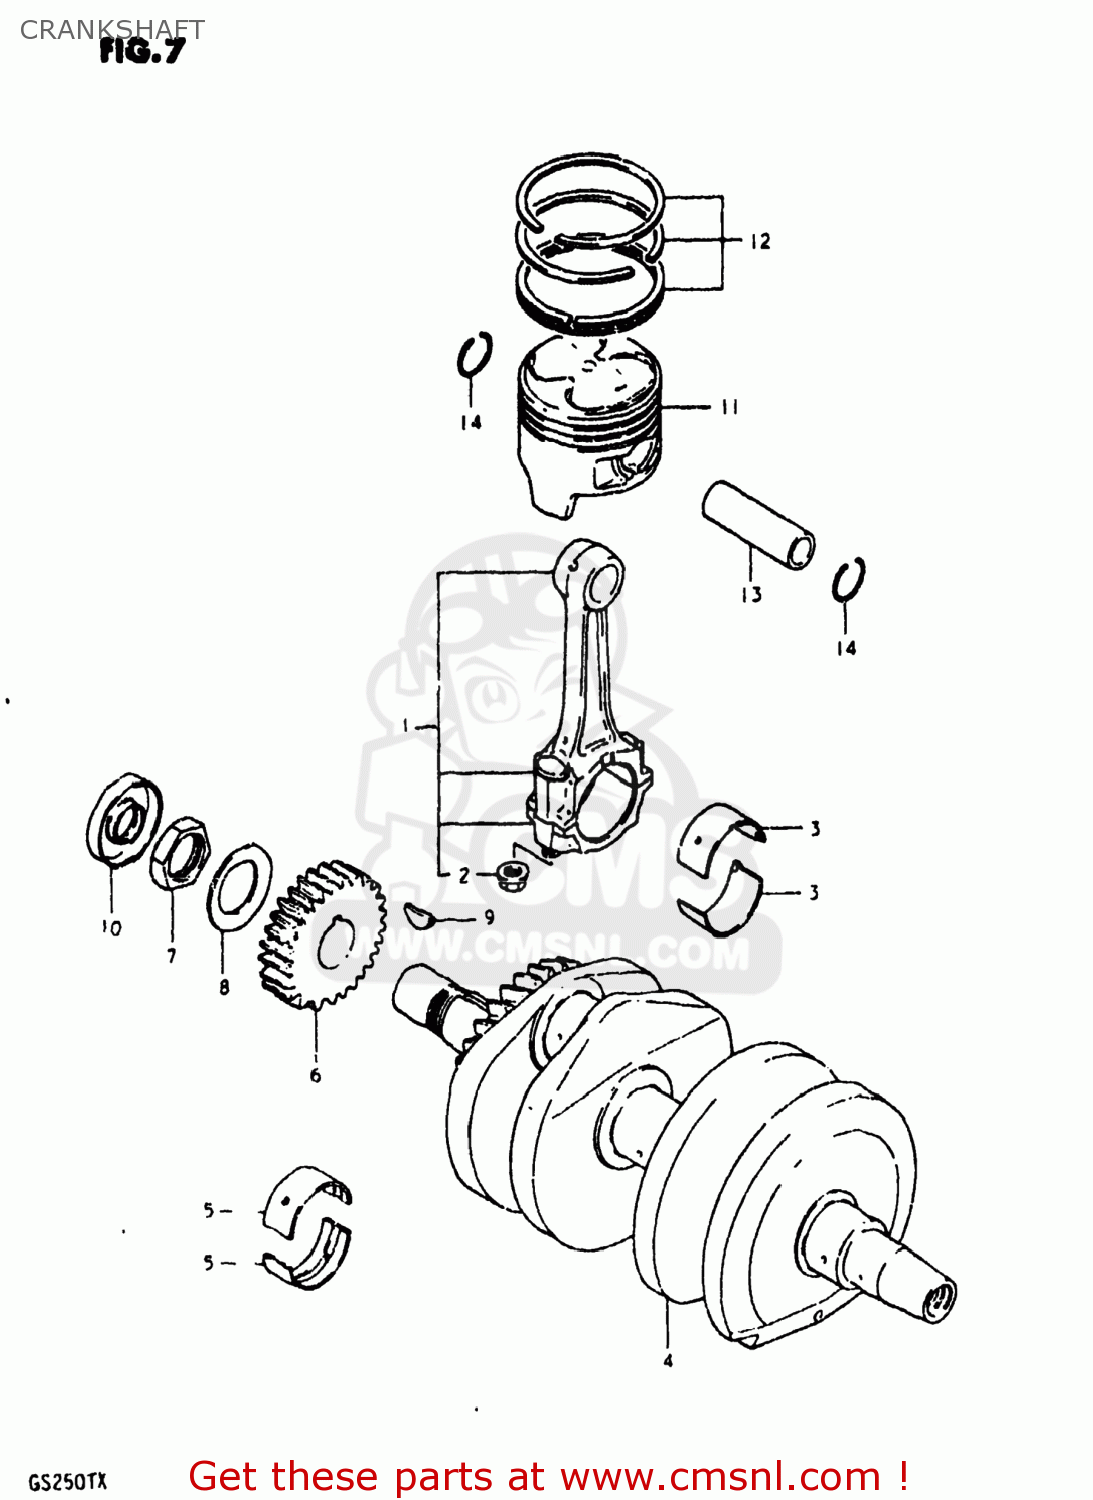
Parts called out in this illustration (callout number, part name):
1	ROD ASSEMBLY,CONNECTING
2	NUT
3	BEARING,CRANK PIN GREEN
4	CRANKSHAFT ASSEMBLY
5	METAL CRANKSHAFT
6	GEAR,PRIMARY DRIVE
7	NUT
8	WASHER
9	KEY
10	OIL SEAL
11	PISTON
12	RING SET,PISTON
13	PIN,PISTON
14	CIRCLIP
